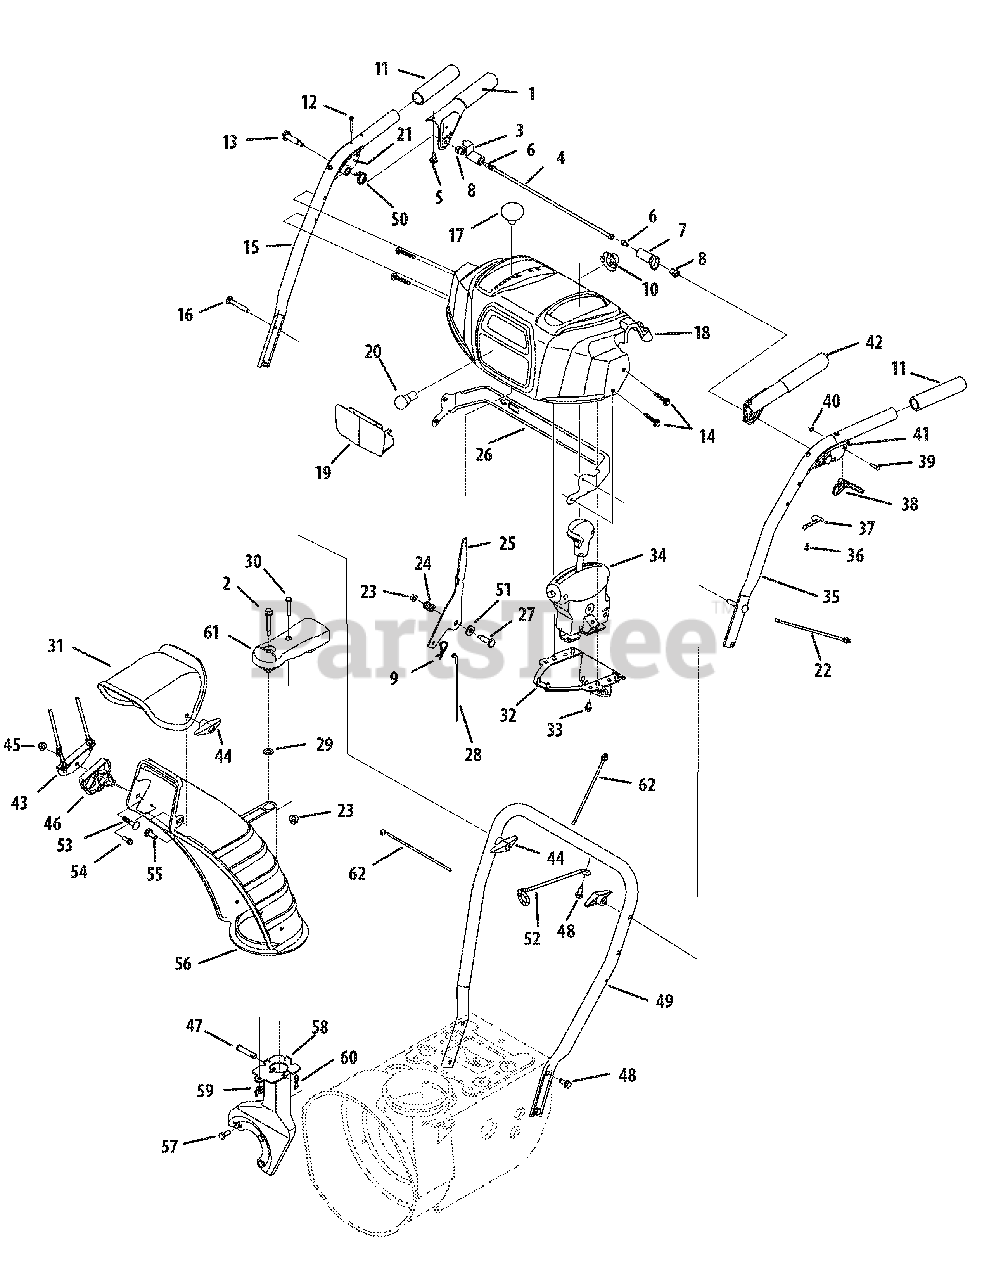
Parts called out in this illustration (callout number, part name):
1	Handle Engagement Assembly RH
2	Flange Shoulder Screw
5	Rubber Bumper
6	Socket Screw, 1/4-20 x .50
7	Clutch Lock Cam
8	Shoulder Nut, 1/4-20
9	Click Pin, .092 x 1.64
10	Light Socket
11	Handle Grip
12	Screw, #10-24 x 0.375
13	Shoulder Screw, 1/4-20 x 1.345
14	Screw, 1/4-20 x 1.625
15	Upper Handle RH
16	Carriage Screw, 5/16-18 x 2.25
17	Shift Knob
18	Handle Panel (Includes Ref. #19)
20	Lamp (24")
20	Lamp (28")
21	Handle Clutch Lock RH Assy
22	Cable Tie
23	Flange Lock Nut, 1/4-20
24	Compression Spring
25	Shift Lever
26	Panel Bracket
27	Shoulder Screw
28	Speed Selector Cable
29	Flat Washer, .25 x .630 x .0515
30	Hex Screw, 1/4-20 x 1.50
31	Upper Chute
32	Joystick Bracket (24")
32	Joystick Bracket (28")
33	Hi-Lo Screw, 1/4-15 x 0.5
34	4-Way Tall Chute Control™ Assembly
35	Upper Handle LH
36	Screw, #8-16 x 0.50
37	Clutch Lock Spring
38	Steering Control
41	Handle Clutch Lock LH Assy
42	Handle Engagement Assembly LH
43	Cable Bracket
44	Wing Knob
45	Flange Lock Nut, 5/16-18
46	Chute Tilt Cable Guide
48	Hex Screw, 5/16-18 x .750
49	Lower Handle
50	Torsion Spring
51	Flat Washer
52	Cable Guide- 28" model
53	Carriage Bolt, 5/16-18 x 1.50
54	Hi-Lo Screw, 1/4-15 x .75
55	Carriage Bolt, 5/16-18 x 1.0
56	Lower Chute
57	Hex Screw, 5/16-24 x .750
58	Chute Support Bracket, Briggs
59	Wing Nut, 1/4-20
60	Bow Tie Cotter Pin
61	Joystick Pulley Cover
62	Cable Tie
